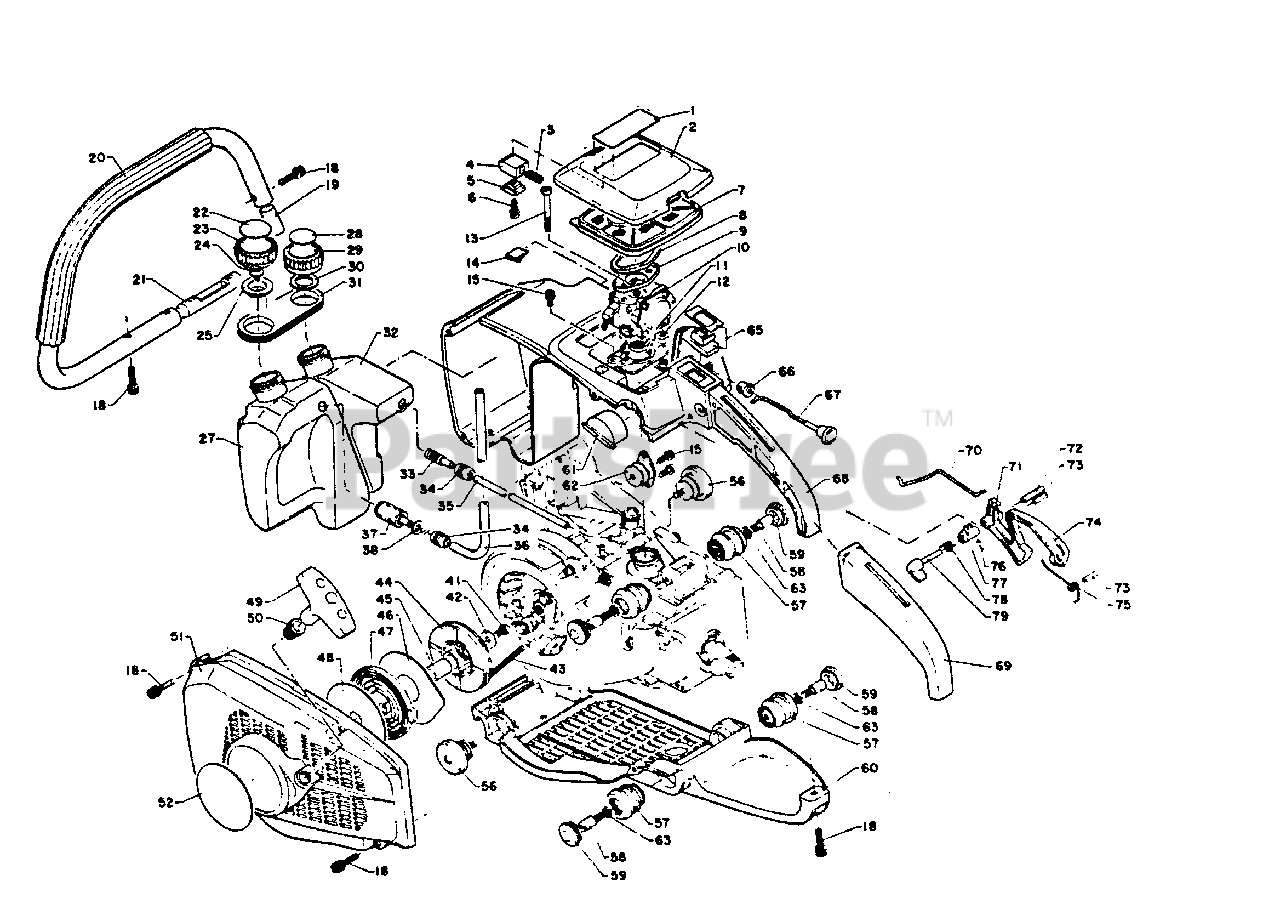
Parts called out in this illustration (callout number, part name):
1	LABEL - CAUTION
2	COVER, AIR FILTER
4	Key, air cleaner cover
5	ADAPTOR, KEY
6	SCREW - 4X14
7	FILTER, AIR
8	GASKET, INTAKE
9	BRACKET, AIR CLEANER
10	CARBURETOR
11	SEAL
12	ADAPTOR, CARBURETOR
13	SCREW - 5X40
15	SCREW - 4X10
18	SCREW - 5X20
19	Insert, front handle
20	HANDLE - FRONT
21	Insert, front handle (L)
22	LABEL - FUEL MIX
23	CAP
25	HOLDER, VENT
27	TANK, FUEL
28	LABEL - OIL
29	CAP, OIL TANK
30	GASKET, CAP
31	CONNECTOR
32	TANK, OIL
33	FILTER, OIL
35	PIPE - OIL
36	FUEL PIPE KIT
37	FILTER, FUEL
38	WASHER - 6
41	SCREW - 5X10
42	WASHER - 5
43	ROPE, STARTER
44	REEL, ROPE
46	PLATE, STARTER
47	SPRING, REWIND
48	PLATE, STARTER
49	GRIP, STARTER
50	GUIDE, ROPE
51	CASE, STARTER
52	LABEL - ECHO
56	CUSHION
57	CUSHION
58	SCREW
59	CAP, CUSHION
60	SUPPORT
61	COVER, CUSHION
62	CUSHION
63	LOCKWASHER - 5
65	IGNITION SWITCH ASSY
67	ROD, CHOKE
68	HANDLE - REAR
69	GRIP, HANDLE - REAR
70	ROD, THROTTLE
71	TRIGGER, THROTTLE
72	PIN - SPRING -- 5X25
73	PIN - SPRING -- 4X13
74	LOCKOUT, THROTTLE
75	SPRING, LOCKOUT LEVER
76	PIN - SPRING -- 1.6X10
77	LOCKOUT, THROTTLE
78	SPRING, LOCKOUT LEVER
79	LEVER, THROTTLE
